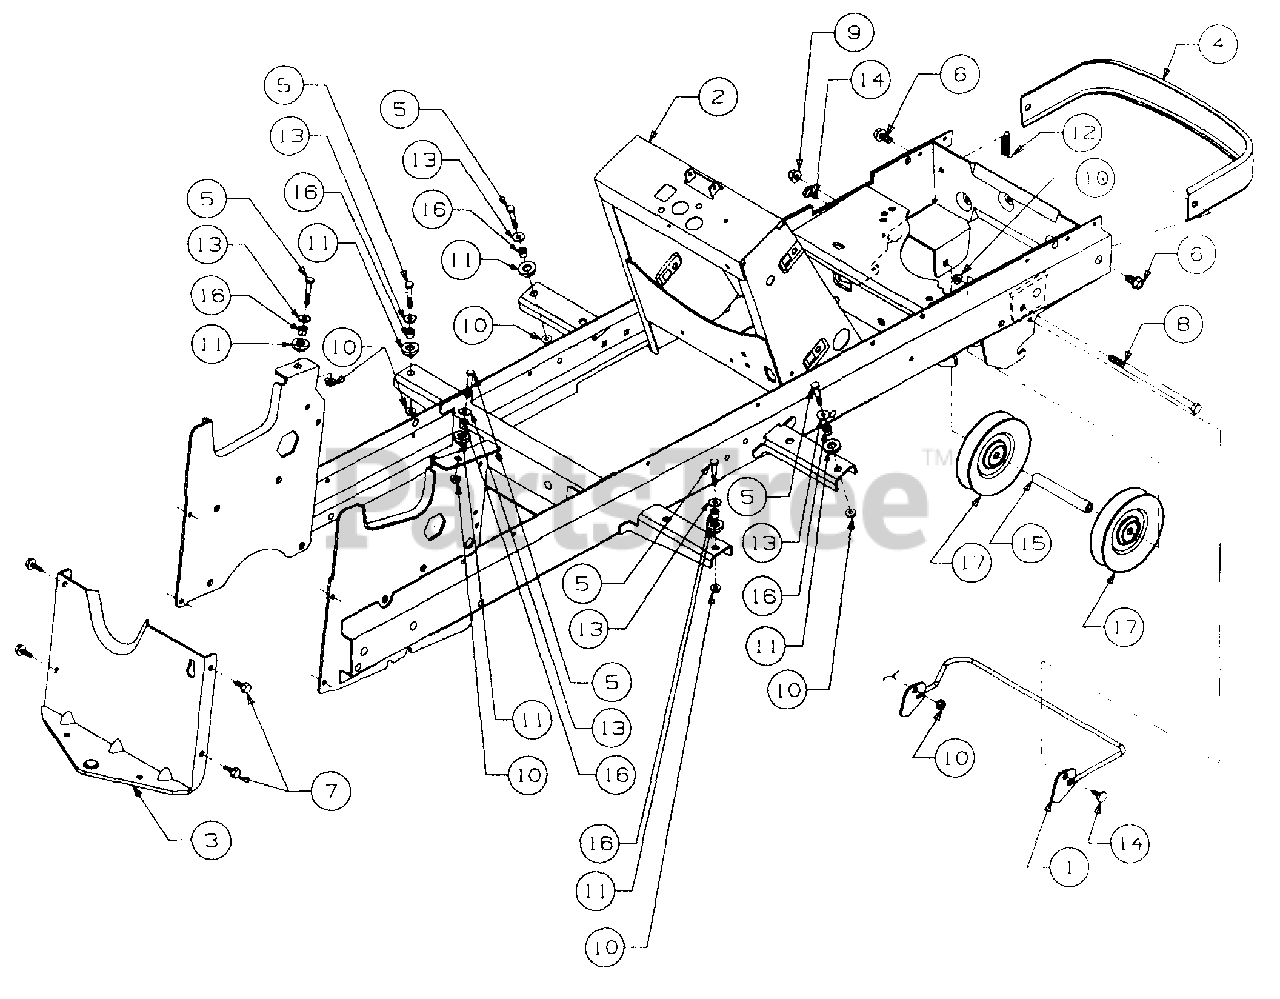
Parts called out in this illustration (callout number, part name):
1	Rod, Quick Attach
2	Frame
3	Drawbar
4	Bumper
5	Screw, Hex Cap, 1/4-20 x 1.0
6	Screw, Hex Wash Hd Tap, 3/8-16 x .75
7	Screw, Hex Wsh Hd Tap, 5/16-18 x .75
8	Screw, Hex Cap, 3/8-16 x 7.0
9	Nut, Hex Flanged Lock, 3/8-16
10	Nut, Hex Flange Lock, 1/4-20
11	Grommet, Insolator
12	Spring, Latch
13	Washer, Flat, .255 x .72 x 60
14	Bolt, Shoulder
15	Spacer, Idler, .407 x .62 x 4.38
16	Spacer, .28 x .40 x .42 Lg
17	Pulley, Idler
